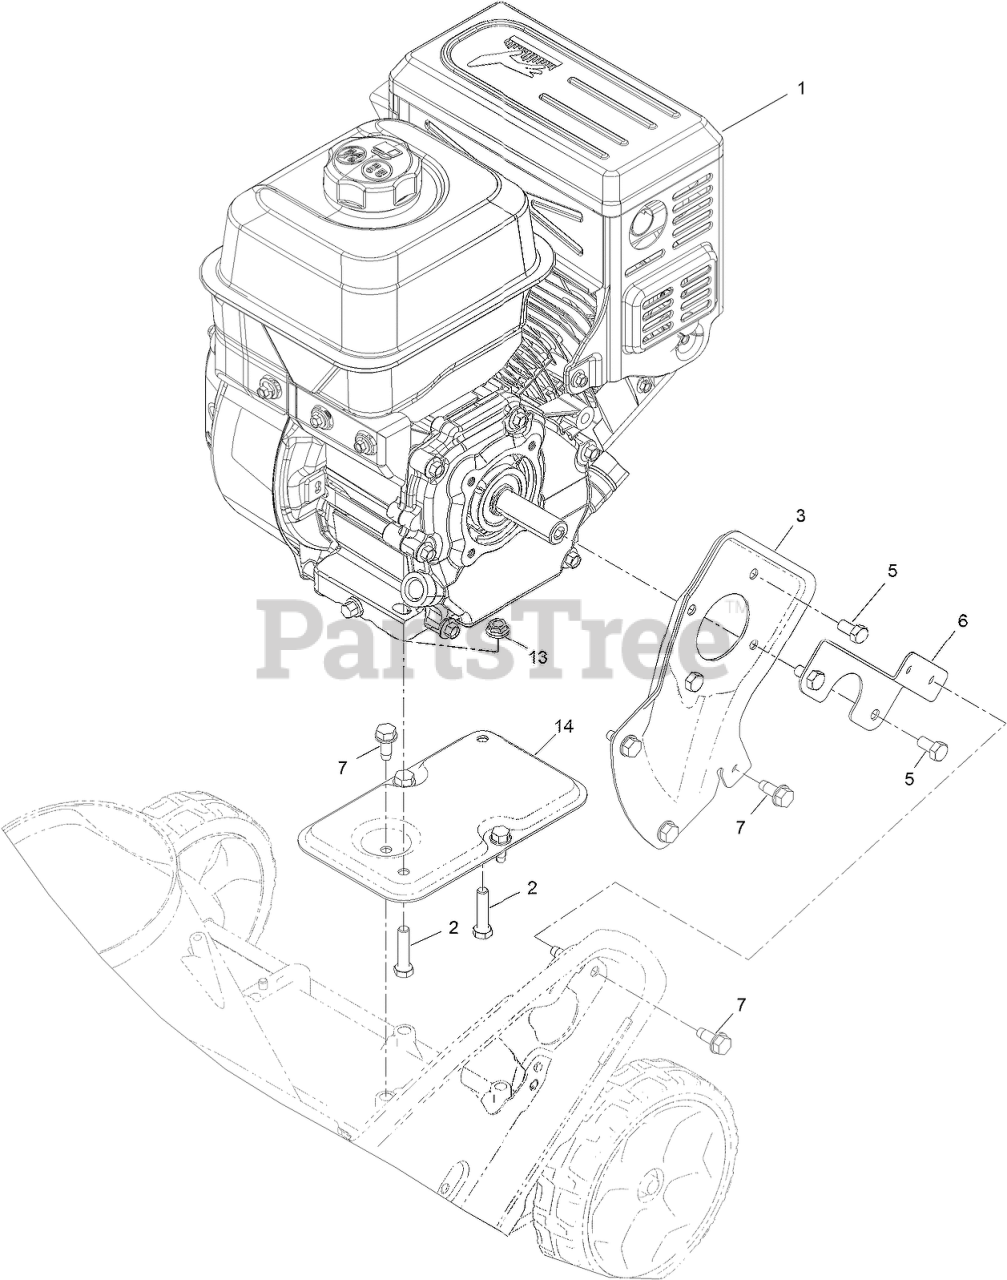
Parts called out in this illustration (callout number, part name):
1	ENGINE-G210FDS-4
2	SCREW-HH
3	PLATE-ENGINE, PTO
5	BOLT
6	SUPPORT-ENGINE, SIDE
7	SCREW-THD ROLL, HWH
13	NUT-HF
14	SUPPORT-ENGINE
